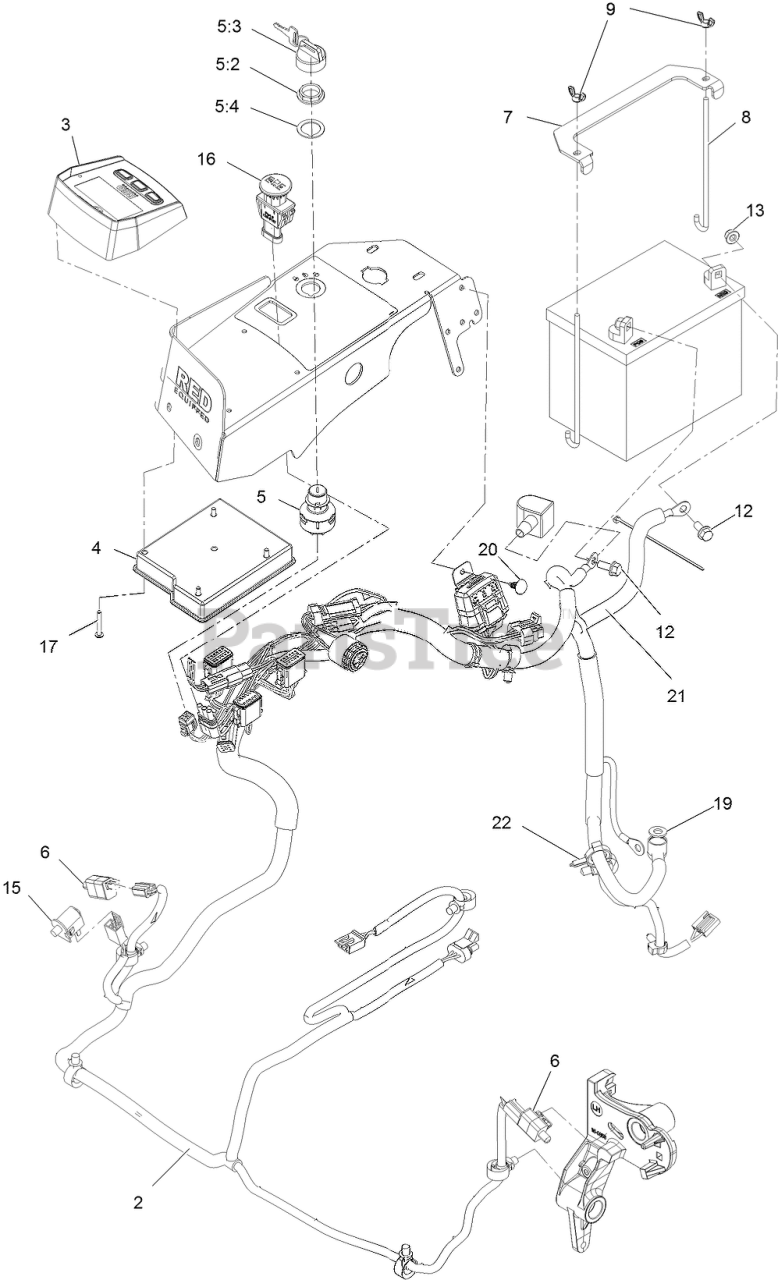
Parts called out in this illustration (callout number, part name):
2	HARNESS-WIRE
3	Module, Ldu
4	Module-Mcu
5	IGNITION SWITCH ASM
5:2	NUT-MOUNTING
5:3	IGNITION KEY SET
5:4	WASHER-BACKUP
7	STRAP-TIE DOWN, BATTERY
8	BOLT-HOLDDOWN
9	WINGNUT
12	SCREW-HHF
13	NUT-HF, NI
15	SWITCH-BAIL
16	SWITCH-PTO, SEALED
17	SCREW-PPH
19	WASHER-FLAT
20	PLUG-PLASTIC
21	TIE-CABLE
22	CLAMP-HOSE
